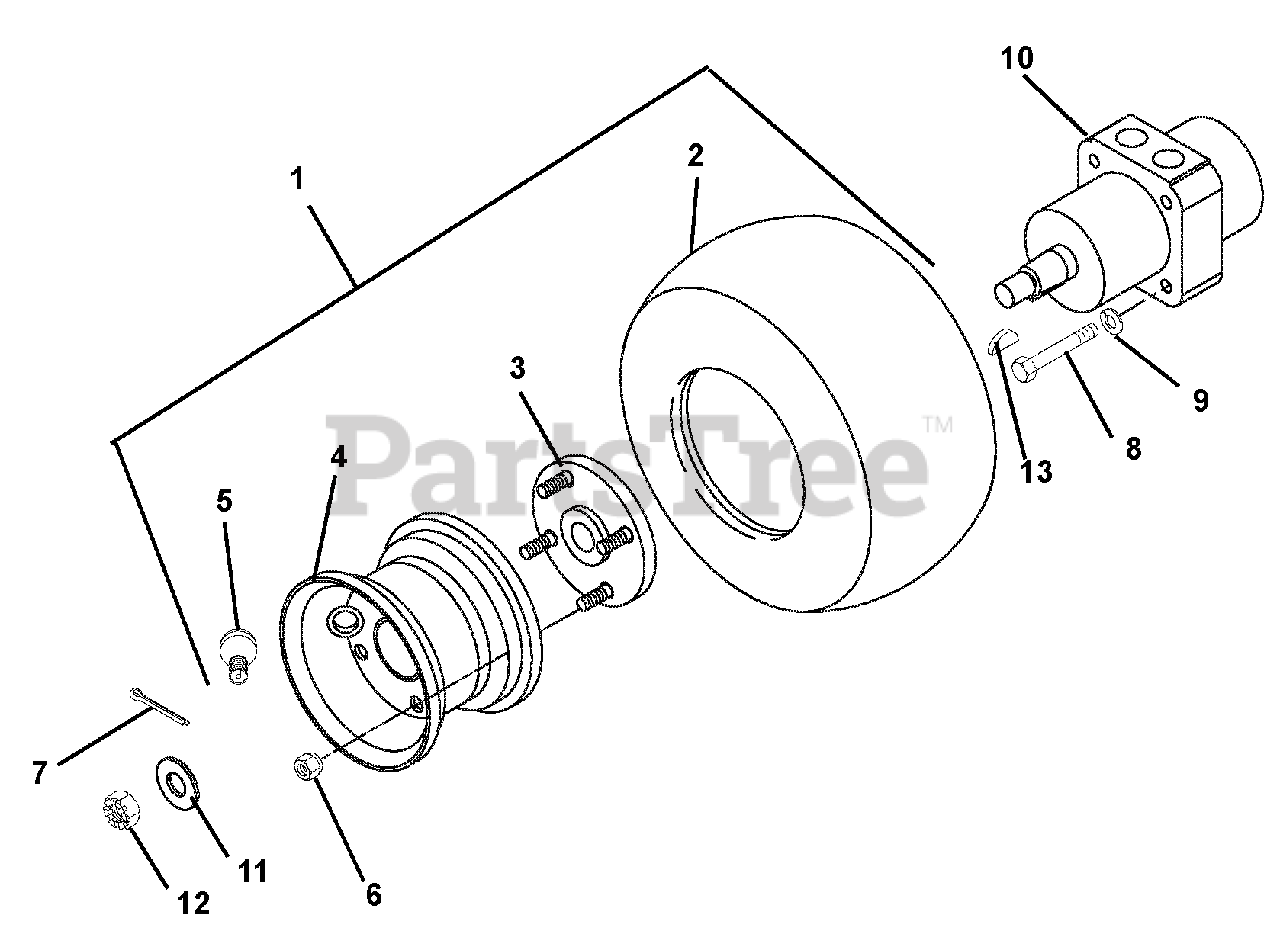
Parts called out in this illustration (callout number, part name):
1	Assembly, Tire and Wheel (includes 2 thru 6)
2	Tire 18 x 8.50 - 8
3	Assembly, Hub
4	Assembly, Rim
5	Valve Stem Assembly
6	Nut, Lug .50-20 PL
7	Pin, Center .12 x 1.25
8	Bolt, Hex .38-16 x 1.00 Grade 5
9	Washer, Locking .38 x .094 Regular
10	Motor, Hydraulic Wheel
11	Washer, Flat-Steel .812 x 1.50 x .135
12	Nut, Hex .75-28 Slotted
13	Key, Woodruff .19 x .75
